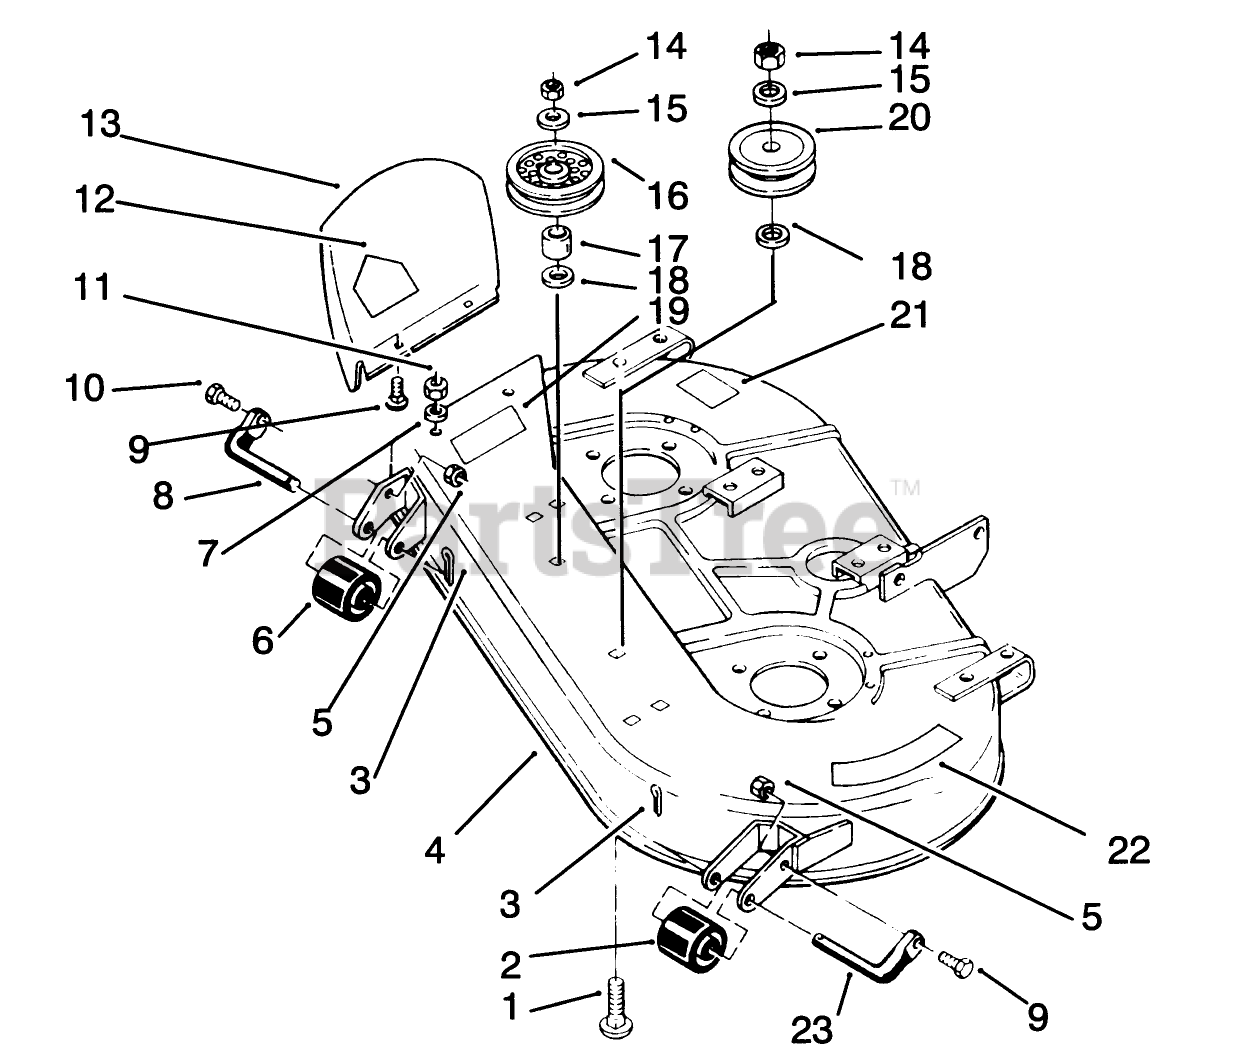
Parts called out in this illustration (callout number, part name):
1	SCREW-CARR
1	WHEEL
1	NUT-JAM
2	ROLLER
2	BOLT-SHOULDER
2	WASHER-FLAT
3	PIN-COTTER
3	ASSY BLADE KIT
4	Deck-Mower (Incl. Ref. #19 & 22)
4	SPRING-COMPRESSION
4	WASHER-FLAT
5	NUT-LOCK, NI
5	Lever
5	SHAFT SPINDLE
6	Roller
6	BOLT 3/8-16X7/8
6	CUP-SPINDLE
7	WASHER-PLAIN
7	SCREW-HH, LOCK
8	ROLLER-SHAFT
8	Quadrant
9	BOLT-CARR
9	PIN-HAIR
9	NUT-JAM
10	SCREW-HH
10	Gage Wheel Support RH
10	WASHER-LOCK
11	NUT-LOCK, NI
11	TRUNNION
11	BLADE PULLEY
12	DECAL-DANGER
12	ROD CONNECTING
12	BEARING-BALL
13	Extension-Chute (Incl. Ref. #12)
13	SCREW-HWH, TAPTITE
13	HOUSING SPINDLE
14	NUT-LOCK, NI
14	PIN-COTTER
14	ZERK FITTING
15	WASHER
15	CLAMP B
16	PULLEY-FLAT IDLER B
16	NUT-LOCK, NI
16	RING-RETAINING
17	SPACER
17	WA GAG WHL R
17	SPACER-BLADE
18	Washer
18	DECAL-HOC
19	DECAL-DANGER, THROWN OBJECT
20	PULLEY-IDLER
21	DECAL BELT INSTALLAT
22	DECAL - DANGER
23	SHAFT-ROLLER
